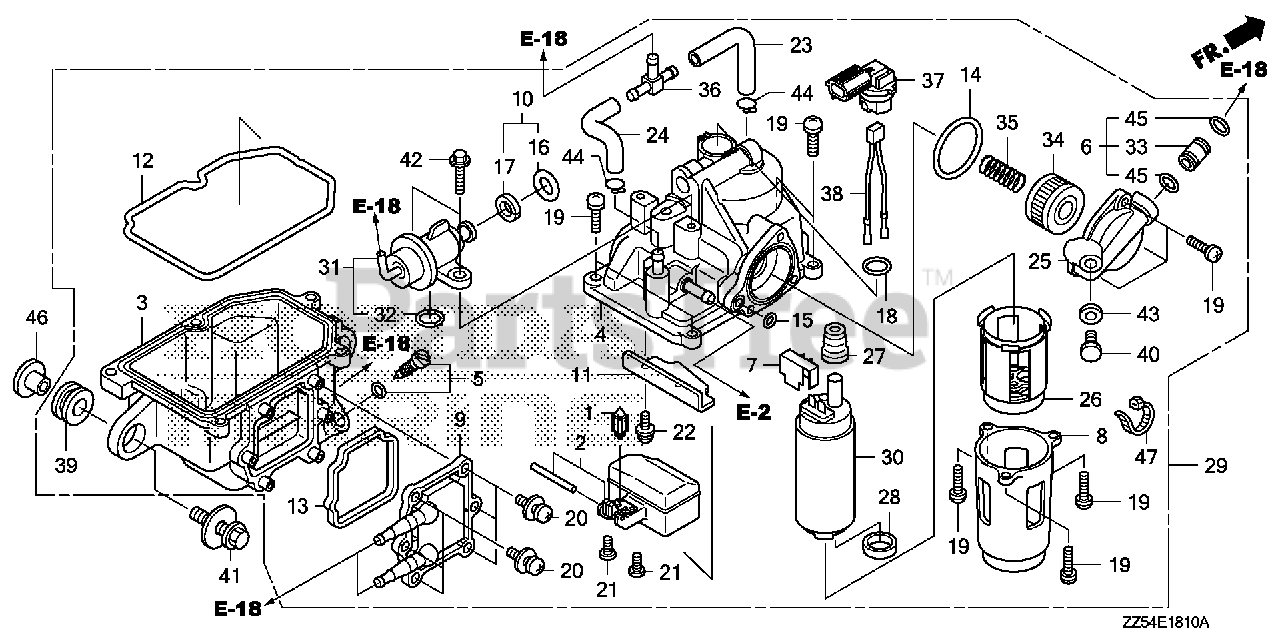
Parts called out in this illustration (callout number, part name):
1	VALVE SET, FLOAT
5	SCREW SET, DRAIN
9	COVER, WATER JACKET
17	RING, BACK-UP
19	SCREW-WASHER
20	SCREW-WASHER
21	SCREW, PAN
22	SCREW, WASHER
23	TUBE A, AIR VENT
24	TUBE B, AIR VENT
27	INSULATOR
29	SEPARATOR ASSY., VAPOR
30	PUMP UNIT, FUEL (MSDS)
31	REGULATOR ASSY., PRESSURE
32	O-RING, PRESSURE REGULATOR
33	JOINT, FUEL PIPE
34	SCREEN, FUEL STRAINER
35	SPRING, COMPRESSION
36	PIPE, THREE WAY JOINT
39	GROMMET, CASE (LOWER)
40	BOLT, SEALING (6MM)
41	BOLT-WASHER (6X25)
42	BOLT, FLANGE (6X14)
43	WASHER, SEALING (6MM)
44	CLIP, TUBE (B10)
45	O-RING (7.8X1.9) (ARAI)
46	COLLAR, MODULE IGNITION CONTROL CASE (CDI)
